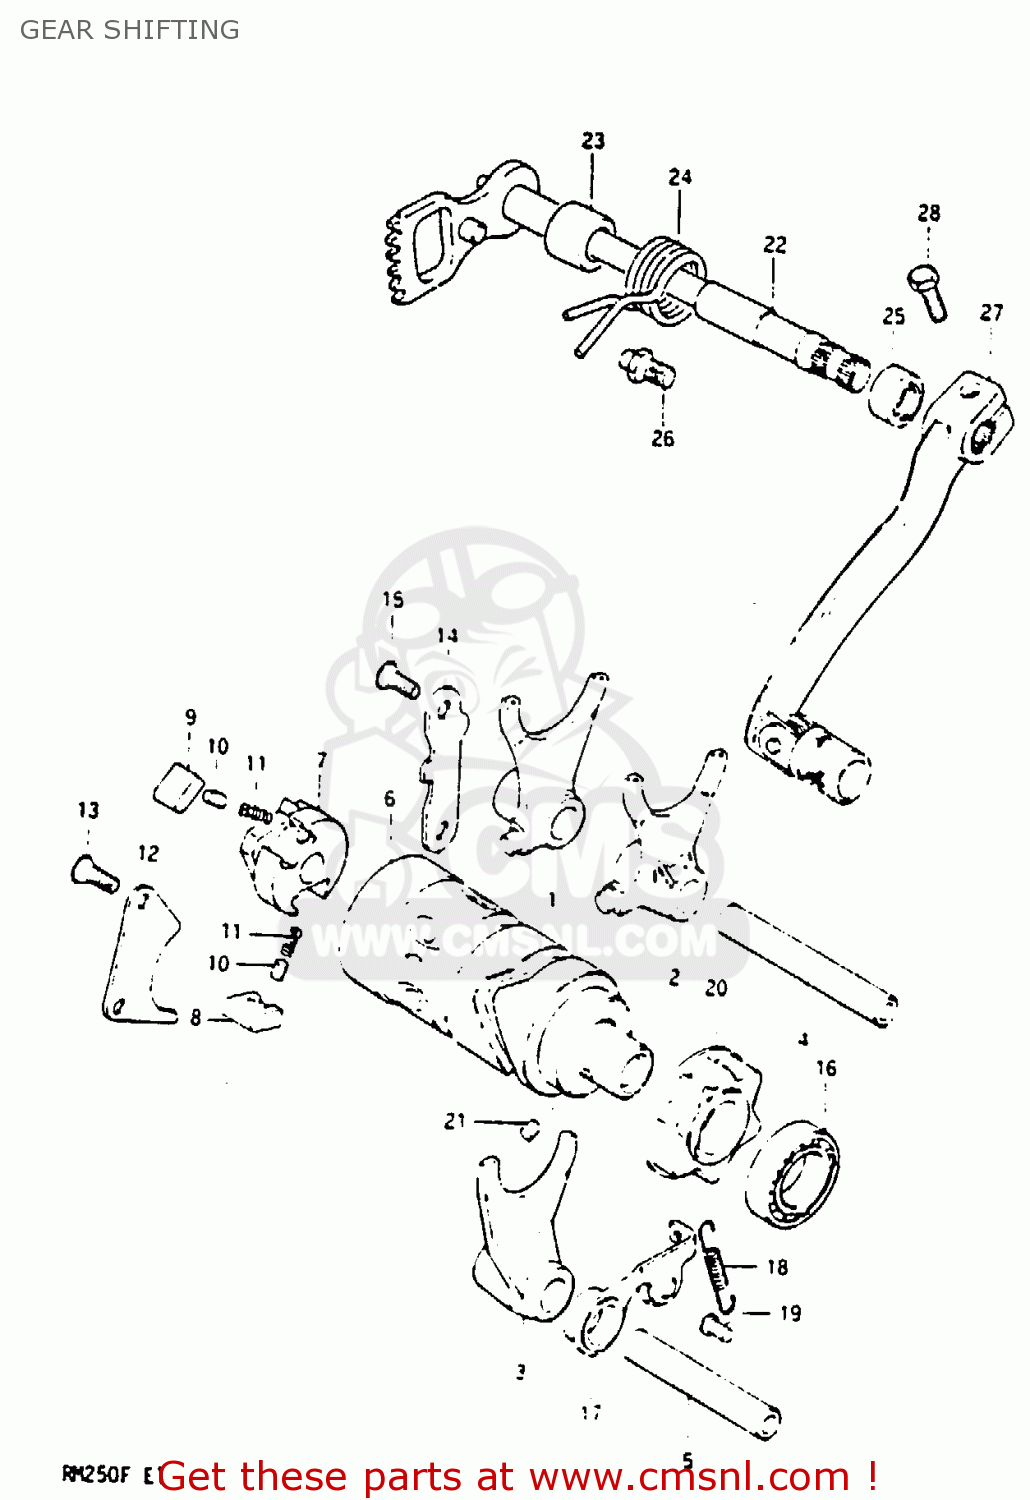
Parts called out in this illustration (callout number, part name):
1	FORK,GEAR SHIFT NO.1
2	FORK,GEAR SHIFT NO.2
3	FORK,GEAR SHIFT NO.3
4	SHAFT,GEAR SHIFT FORK
5	SHAFT,GEAR SHIFT FORK NO.2
6	CAM,GEAR SHIFT
7	GEAR,GEARSHIFT CAM DRIVE
8	PAWL,GEAR SHIFT NO.1
9	PAWL,GEAR SHIFT NO.2
10	PIN(5X8)
11	SPRING
12	LIFTER,GEAR SHIFT PAWL
13	SCREW
14	GUIDE,GEAR SHIFTING CABLE
15	SCREW
16	BEARING
17	STOPPER,GEAR SHIFTING CAM
18	SPRING
19	RIVET
20	PLATE,GEAR SHIFT CAM STOPPER
21	PIN
22	SHAFT,GEAR SHIFT
23	SPACER(12X20X15.3)
24	SPRING
25	OIL SEAL
26	STOPPER,GEAR SHIFT CAM
27	LEVER ASSEMBLY,GEAR SHIFTING
28	BOLT
